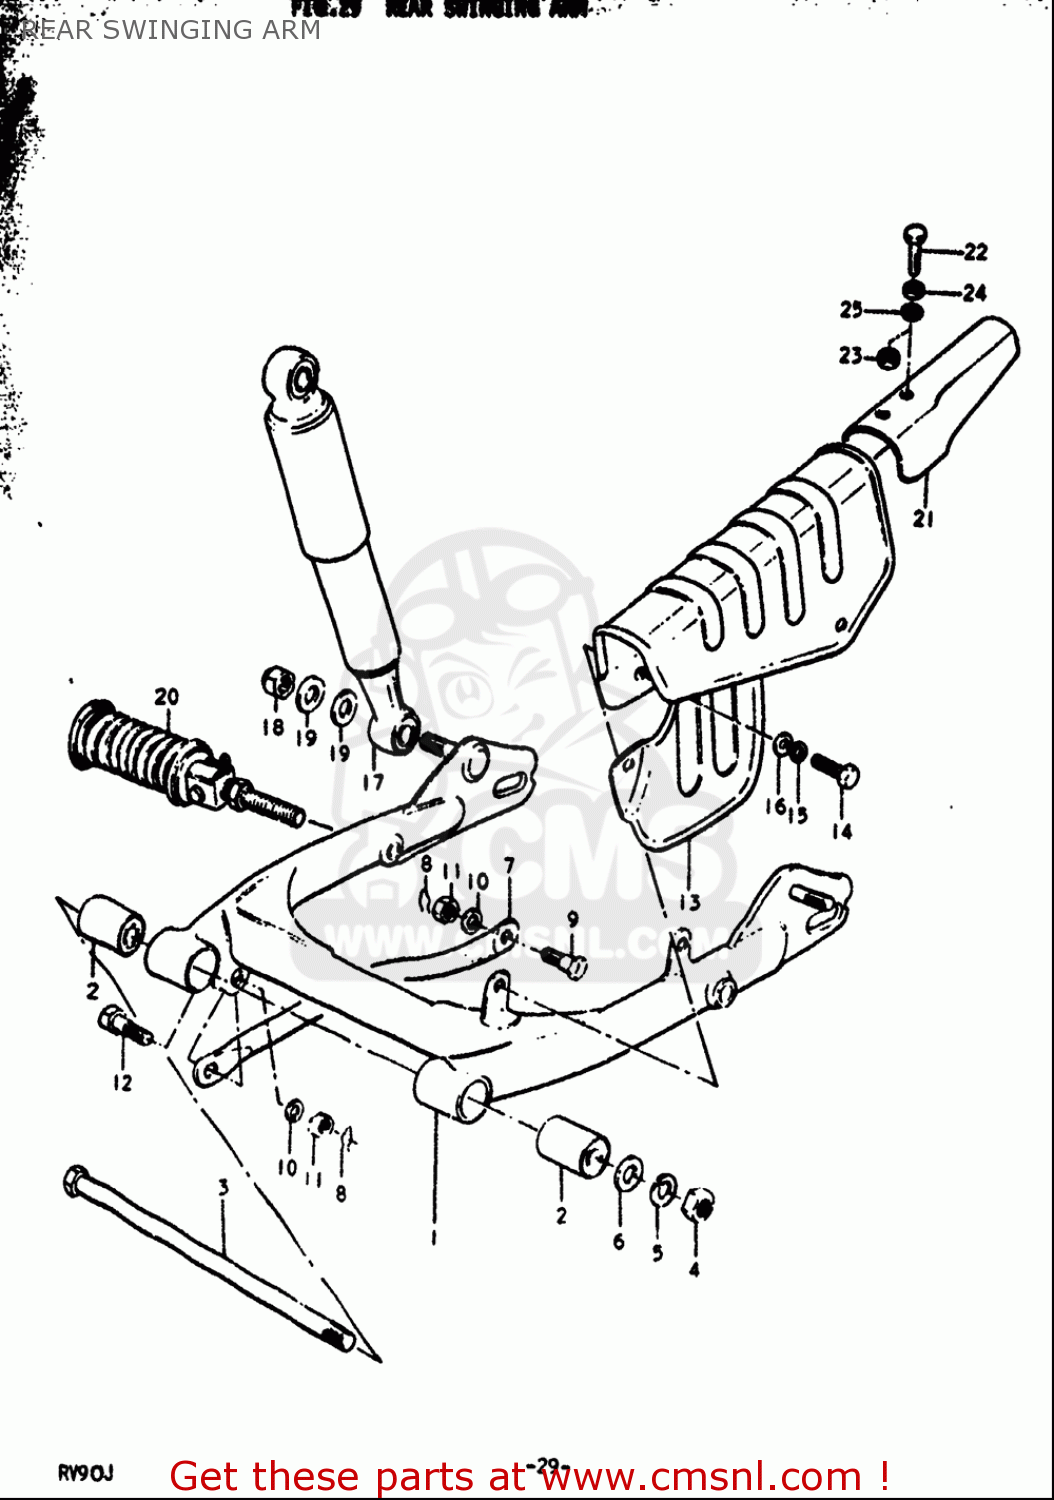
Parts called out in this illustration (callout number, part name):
2	BUSHING(10X23X35)
3	SHAFT,RR SWINGINGARM PIVOT
4	NUT
5	WASHER,LOCK
6	WASHER
8	CLIP
9	BOLT(8X26.5)
10	WASHER,LOCK
11	NUT
12	BOLT(8X29)
14	BOLT(6X8)
15	WASHER,LOCK
16	WASHER
17	ABSORBER ASSY,RR SHOCK
18	NUT
19	WASHER (10.5X24X2.3)
20	FOOTREST ASSEMBLY,REAR
22	BOLT
23	NUT
24	WASHER,LOCK
25	WASHER
